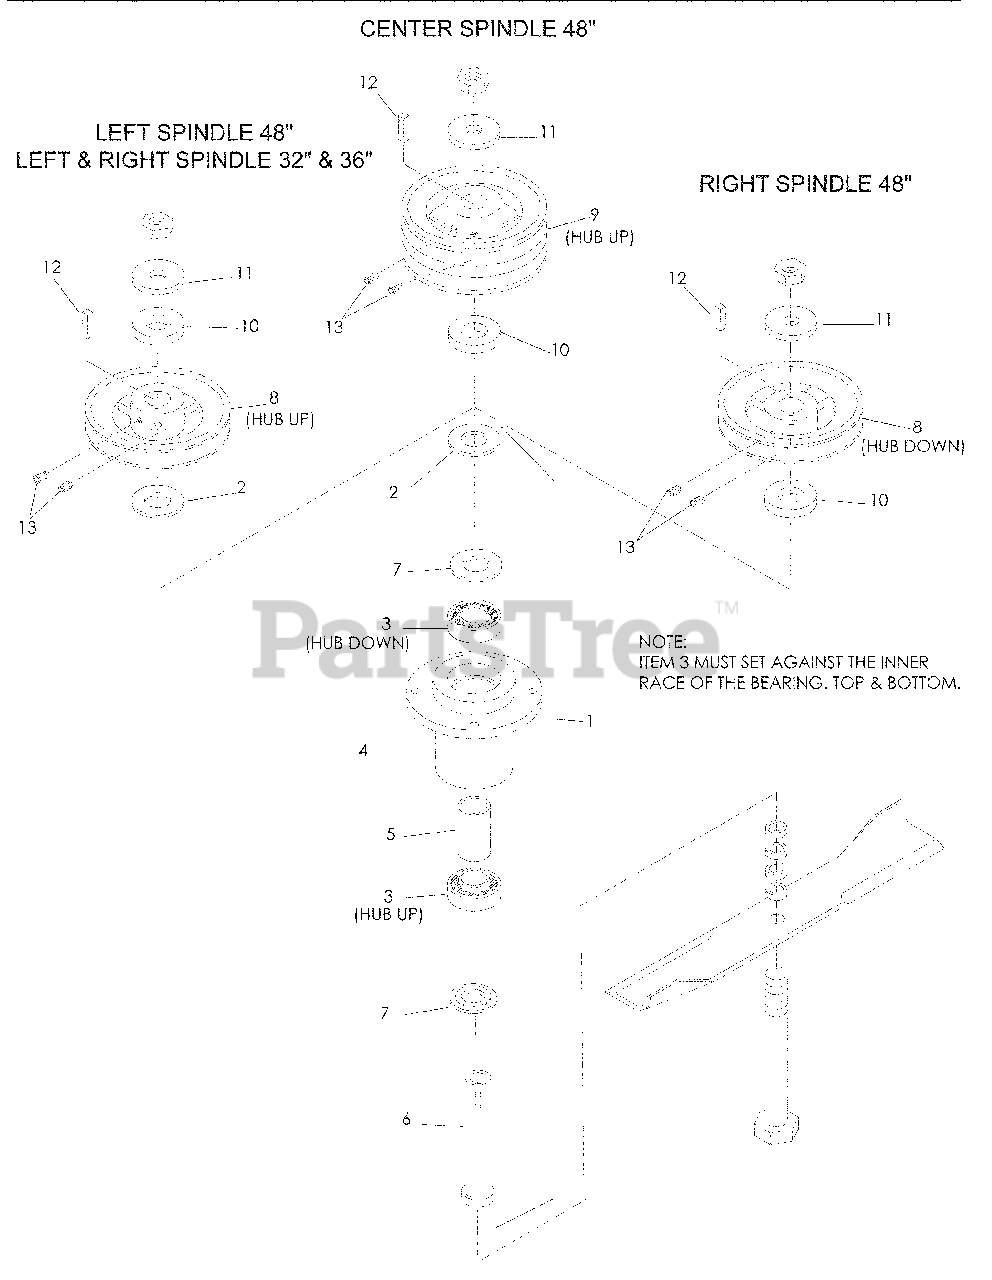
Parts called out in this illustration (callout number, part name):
1	HOUSING ASSM
2	BUSHING 10 GA
3	BEARING
7	COMBO SPACER
8	PULLEY W/SETSCREWS
9	PULLEY, DBL W/SETSCREWS
10	SPACER 3/8"
11	SUPPORT WASHER
12	KEY ¼ SQ. x 11/8
13	SETSCREW 5/16 NYLOC
